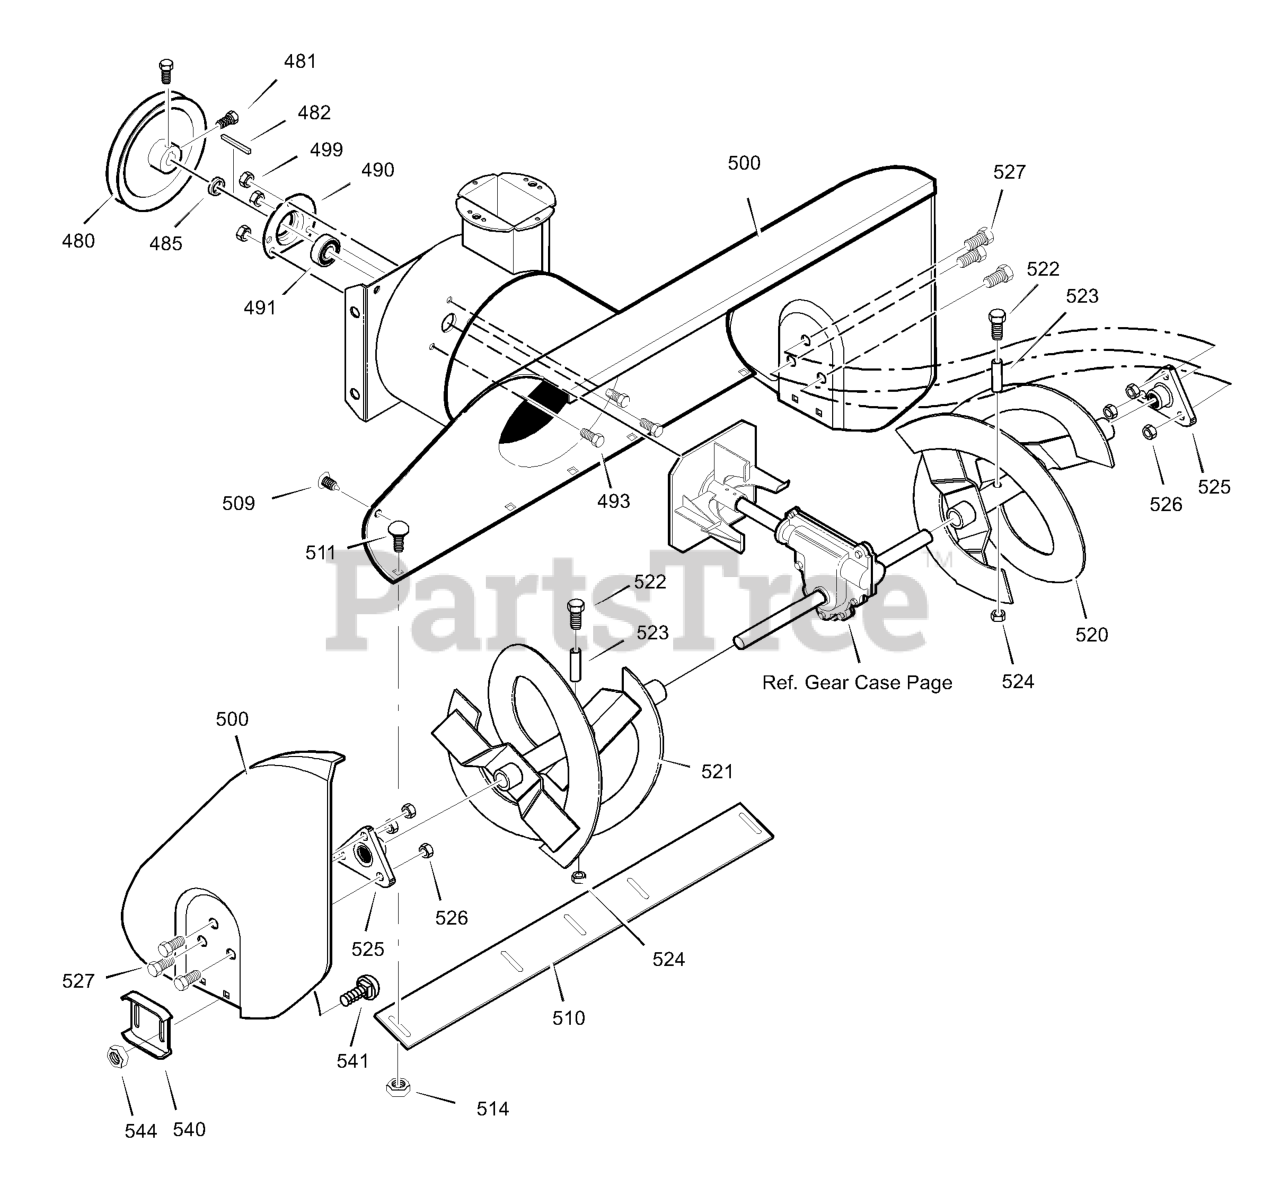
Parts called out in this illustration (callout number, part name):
480	PULLEY, 4L 6.12 X 0.67
481	SCREW, 5/16-18 x 5/8
482	KEY, Square, 3/16 X 3/4
485	SPACER, Friction Pulley
490	RETAINER, BALL BRNG
491	BEARING, BALL
493	BOLT, HEX - 0.31-18X0.50
499	SHIM-ENDPLAY
500	HOUSING, ASSY
510	BLADE, SCRAPER 24"
511	BOLT, Carriage, 1/4-20 x 3/4
514	NUT, Hex Flange, Whiz Lock, 1/4-20
520	AUGER, ASSEMBLY, LH
521	AUGER, ASSEMBLY, RH
522	CAPSCREW, Hex Head, 1/4-20 x 1-3/4, GR2
523	SPACER, Sleeve, 1/4 x 1/2
524	NUT, 1/4-20 REGHEXCTRLK YZ
525	BEARING, Flange
526	NUT, 5/16-18
527	SCREW, Tapping, 5/16-18 x 3/4
540	SKID, HEIGHT ADJUST
541	BOLT, Carriage, 5/16-18 x 3/4, GR5
544	SHIM-ENDPLAY
